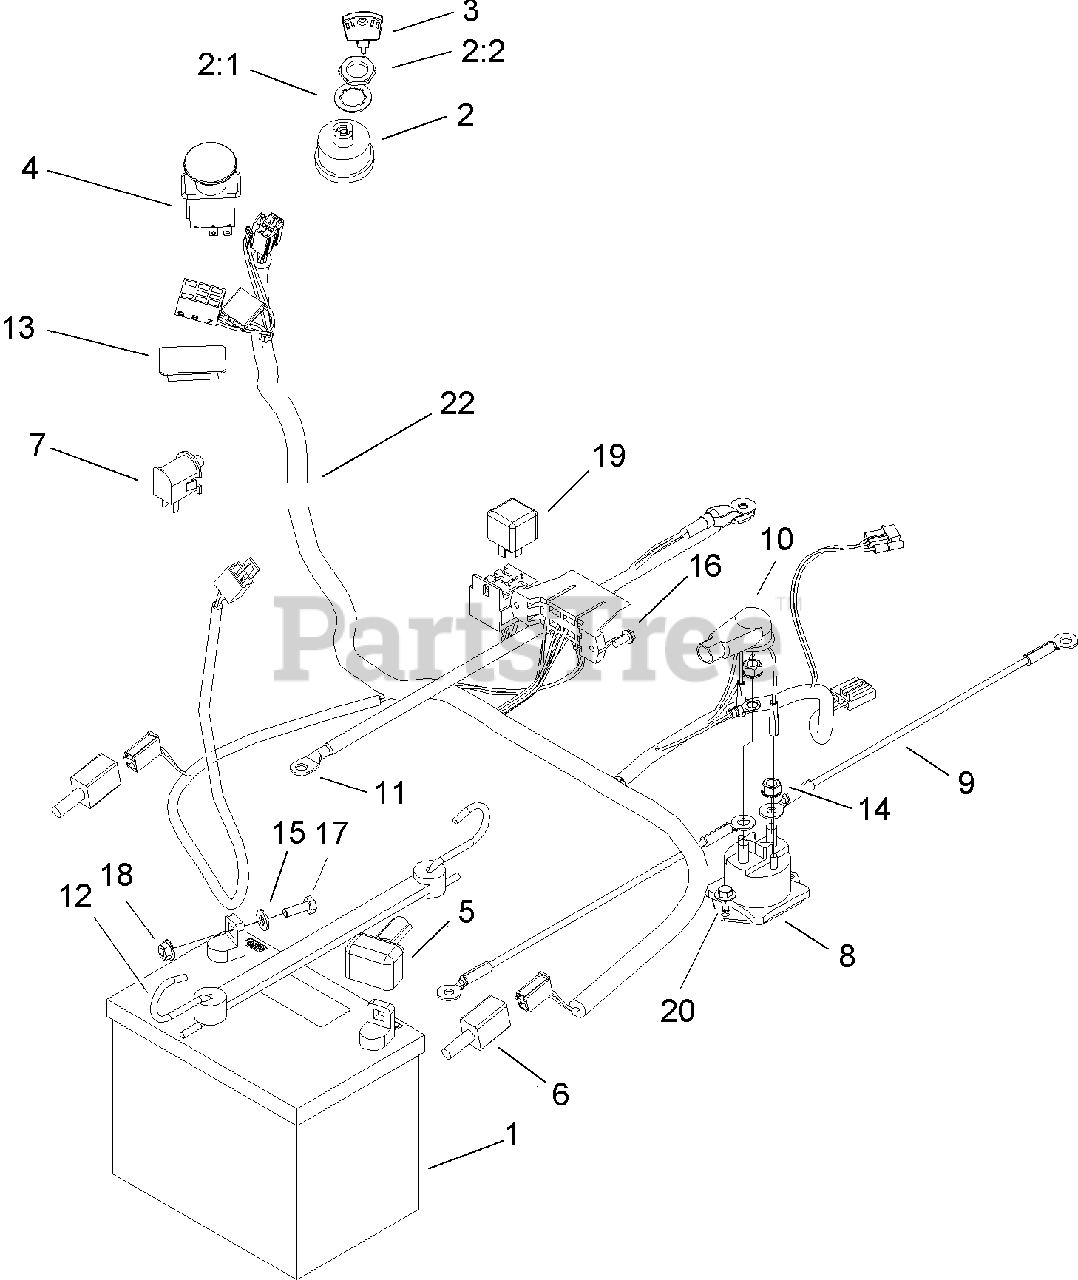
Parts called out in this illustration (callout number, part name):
1	BATTERY
2	SWITCH ASM
2:1	WASHER-TOOTH
4	SWITCH-PTO
5	BOOT-TERMINAL
7	SWITCH-BAIL
9	WIRE ASM
10	BOOT-INSULATOR, TERMINAL
12	HOLDDOWN-BATTERY
13	PLUG-HOLE
14	NUT-KEPS
15	WASHER-FLAT
16	SCREW-TAPTITE
17	SCREW-HH
20	SCREW-HHF
22	HARNESS-WIRING
